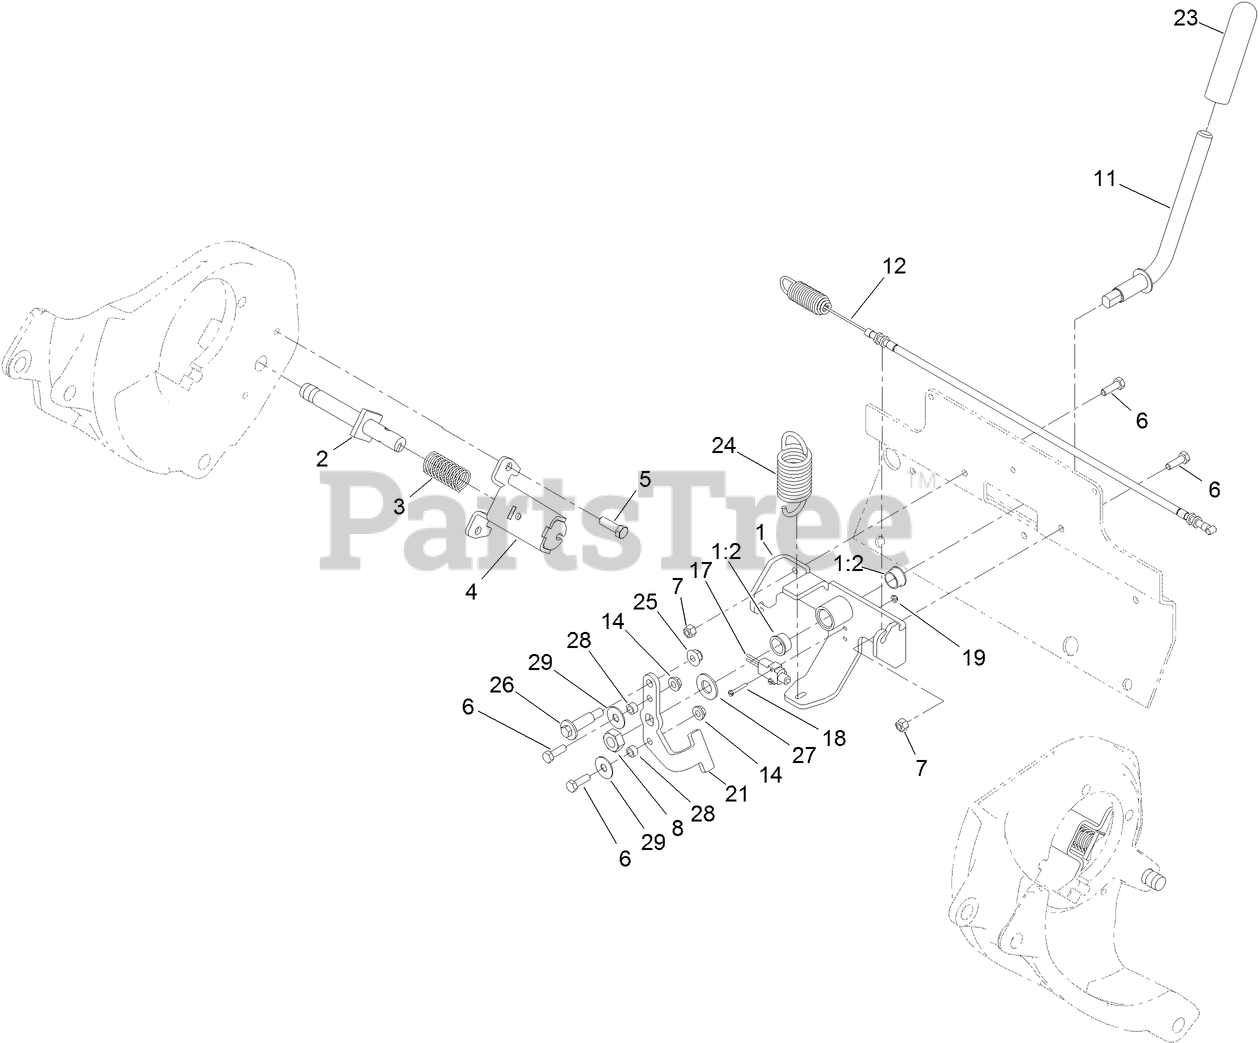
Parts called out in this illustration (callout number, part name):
1	BRAKE BRACKET ASM
1:2	BEARING-FLANGE
2	SHAFT ASM
3	SPRING-COMPRESSION
4	BRACKET-BRAKE
5	SCREW-HH
6	SCREW-HH
7	NUT-LOCK, NI
8	NUT-LOCK, NI
11	LEVER-BRAKE
12	CABLE-BRAKE
14	PIN-COTTER
17	SWITCH
18	SCREW
19	NUT-HEX
21	PLATE-LINKAGE, BRAKE
23	GRIP-HANDLE
24	SPRING-EXTENSION
25	NUT-HF, NI
26	SCREW-HH
27	WASHER-FLAT
28	SPACER-PIVOT, TILT
29	WASHER
